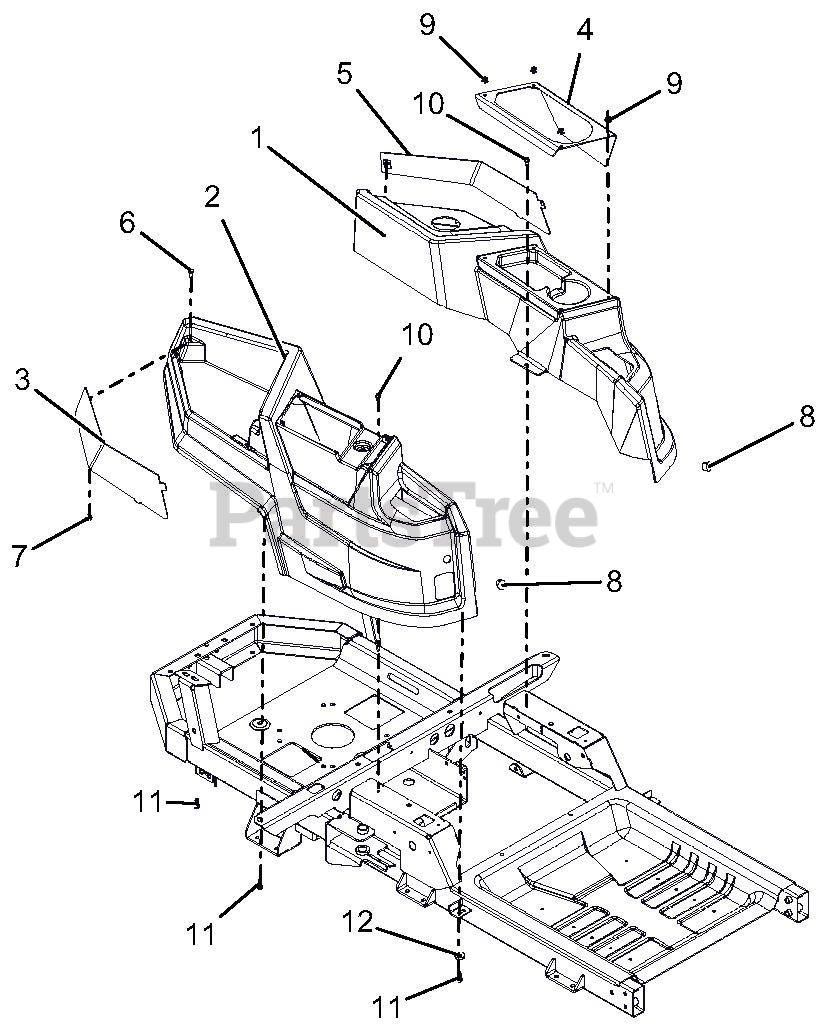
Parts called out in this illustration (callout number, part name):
1	FENDER, LH -ZOOM
2	FENDER, RH -ZOOM
3	WLDMT, PANEL BLOCKOFF-RH
4	PANEL, CONTROL /CUP-LH
5	WLDMT, PANEL BLOCK OFF-LH
6	BLT-HEX .25-20X.63 GR5 BLKZC
7	NUT, LK-TOP-FLG .25-20 YWZC
8	PLUG, HOLE .750-BLACK
9	RVT-POP .195 PLASTIC
10	SCR-TAP .25-20X.50 HWH TR YWZ
11	SCR-HEX .312-14X.75 H/L
12	WSHR-FL-STL .406X1.00X.188 YWZC
